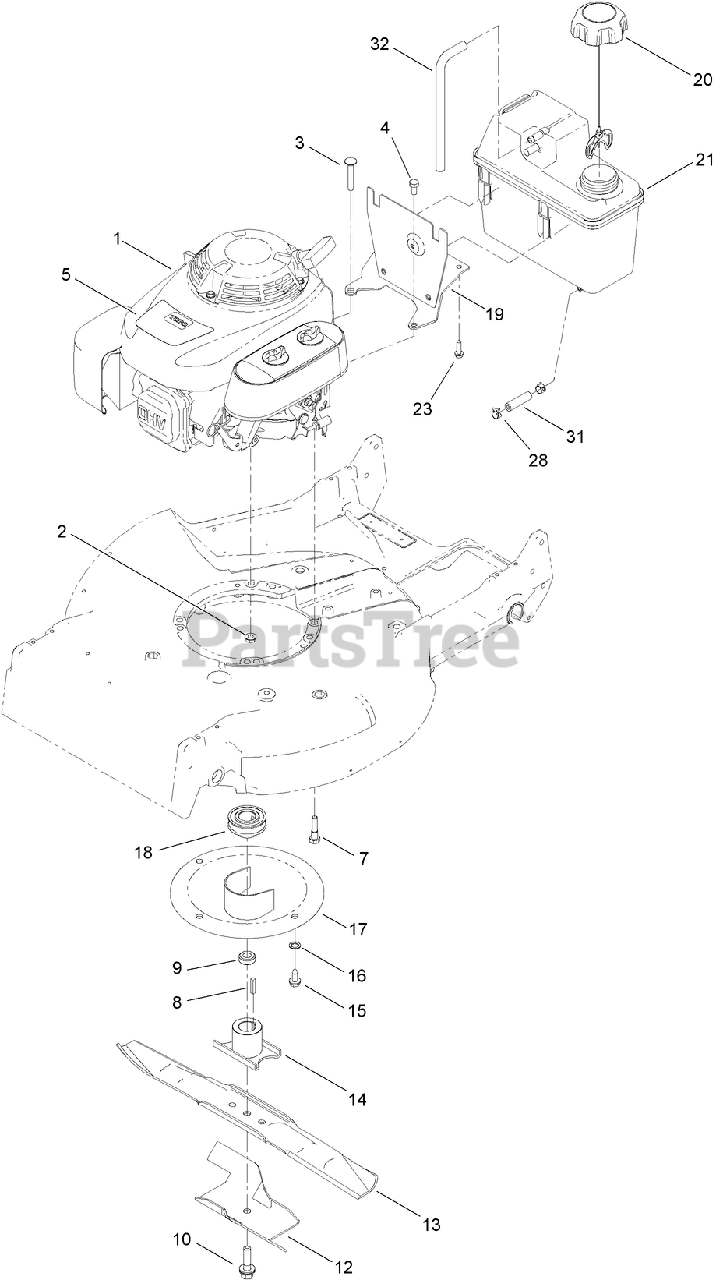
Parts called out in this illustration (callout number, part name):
2	NUT-HF
3	BOLT-CARR
4	SCREW-HH
7	SCREW-SHOULDER
8	KEY-SQUARE
9	SPACER-RETAINER, BLADE
12	STIFFENER-BLADE
13	BLADE-21 INCH
14	RETAINER-BLADE
15	SCREW-HWHTF
16	WASHER-LOCK, INTERNAL
18	PULLEY-DRIVER
19	MOUNT-TANK
21	TANK-FUEL
23	SCREW-HWH
28	CLAMP-HOSE
31	HOSE-FUEL
32	HOSE-VENT, CANISTER
